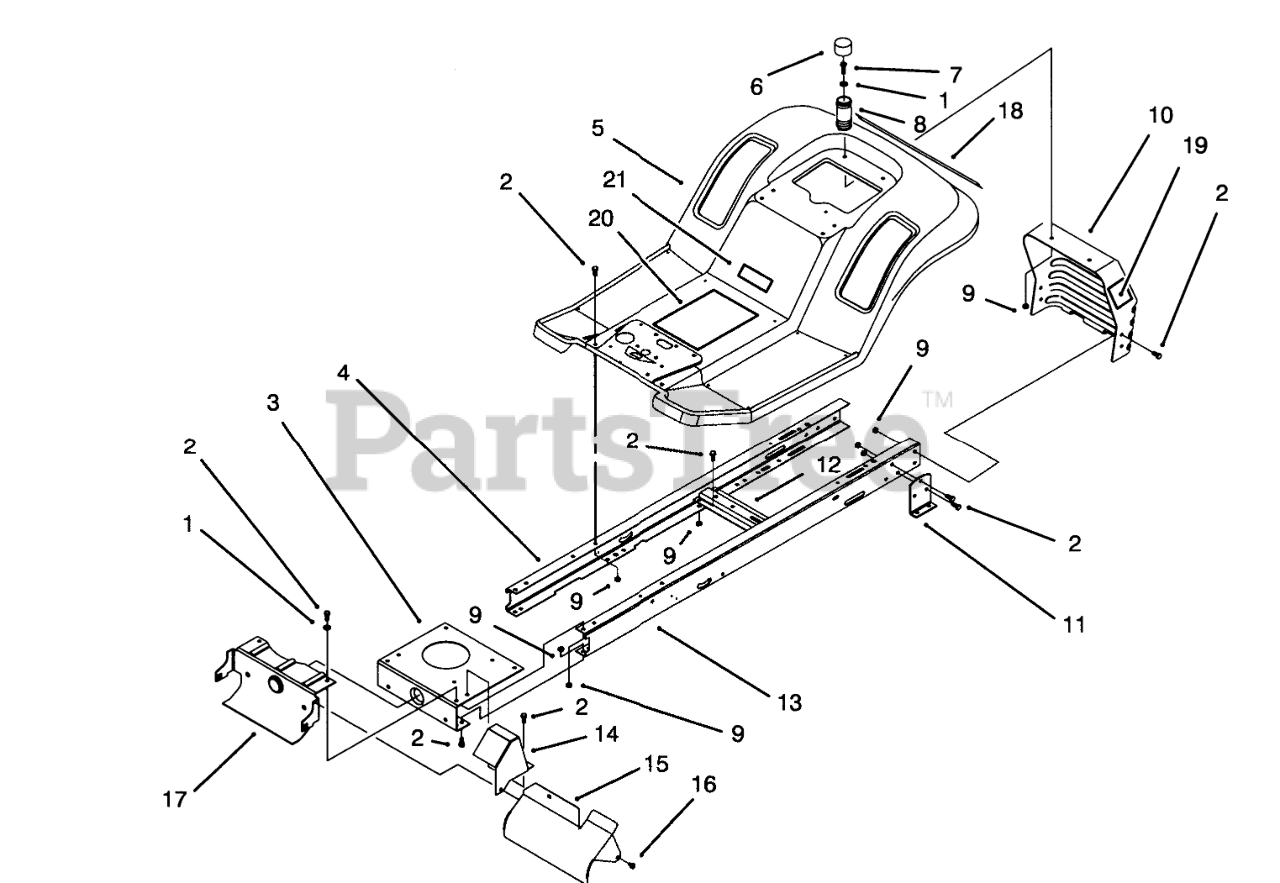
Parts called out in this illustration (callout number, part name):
1	WASHER-PLAIN
2	SCREW-HH
3	Plate-Engine Mount
4	Frame-Rail R.H.
5	BODY-REAR
6	CAP-PROTECTOR
7	SCREW-HH
8	SPRING-COMPRESSION
9	NUT-LOCK, NI
10	Panel-Rear Hitch
11	Bracket-Transaxle
12	Bracket-Idle Pivot
13	Frame-Rail L.H.
14	Shield-Exhaust Pipe
15	Shield-Muffler
16	SCREW-HWHTF
17	Support-FrontAxle
18	DECAL - REAR BODY
19	DECAL - DUMP VALVE
20	Decal-Instruction Hydro
21	Decal-Made In USA
